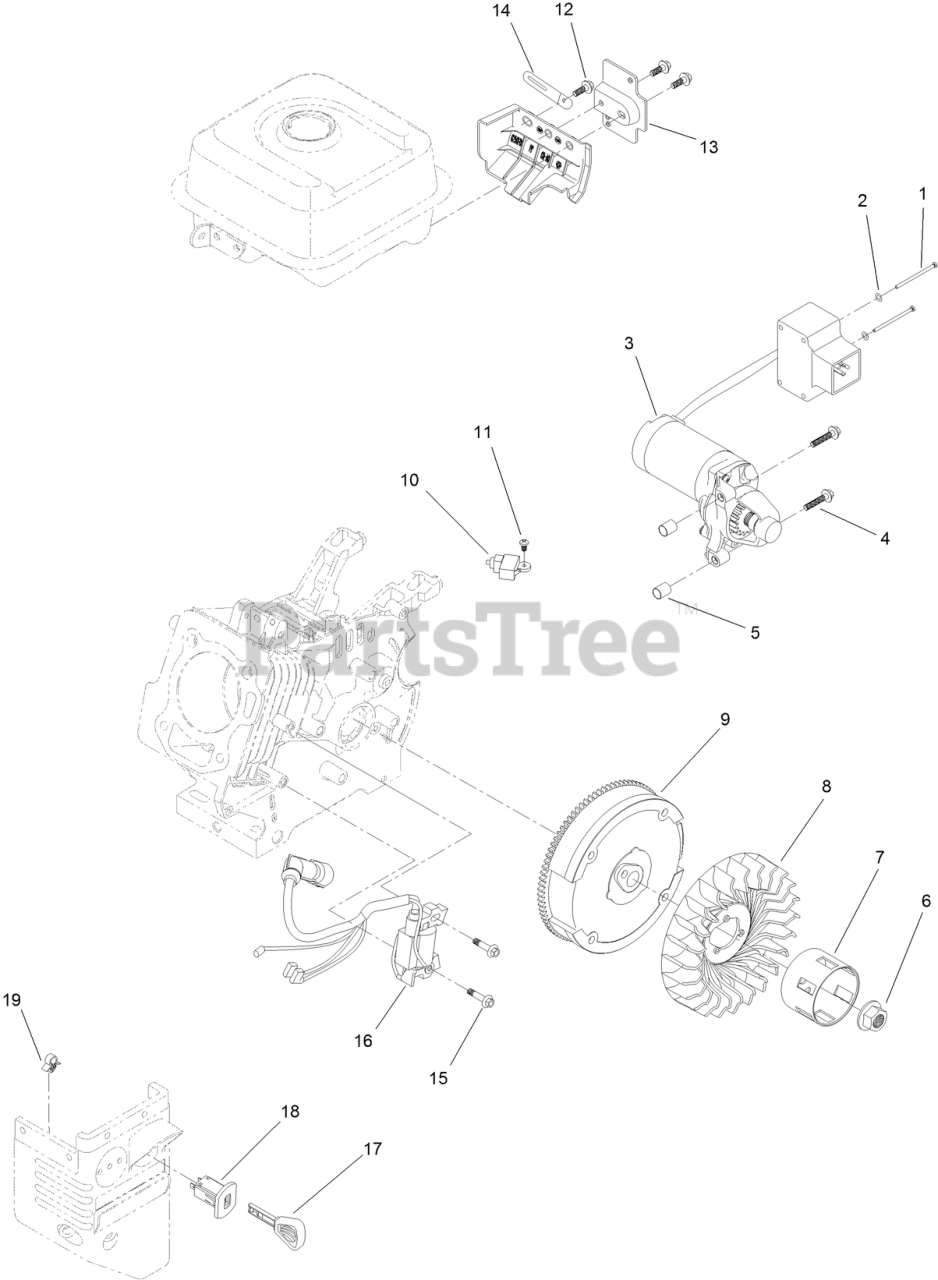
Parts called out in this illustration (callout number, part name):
1	SCREW-BHP
2	WASHER-PLAIN
3	MOTOR-STARTER
4	SCREW-FLANGE
5	PIN-DOWEL
6	NUT-FLANGE
7	CUP-STARTER
8	FAN-COOLING
9	FLYWHEEL AND RING GEAR ASM
10	SWITCH-KILL, ENGINE
11	SCREW-PPH
12	SCREW-HHF
13	BRACKET-SWITCHBOX, STARTER
14	CLIP-HARNESS, WIRE
15	SCREW-HHF
16	IGNITION COIL ASM
18	SWITCH-KEY
